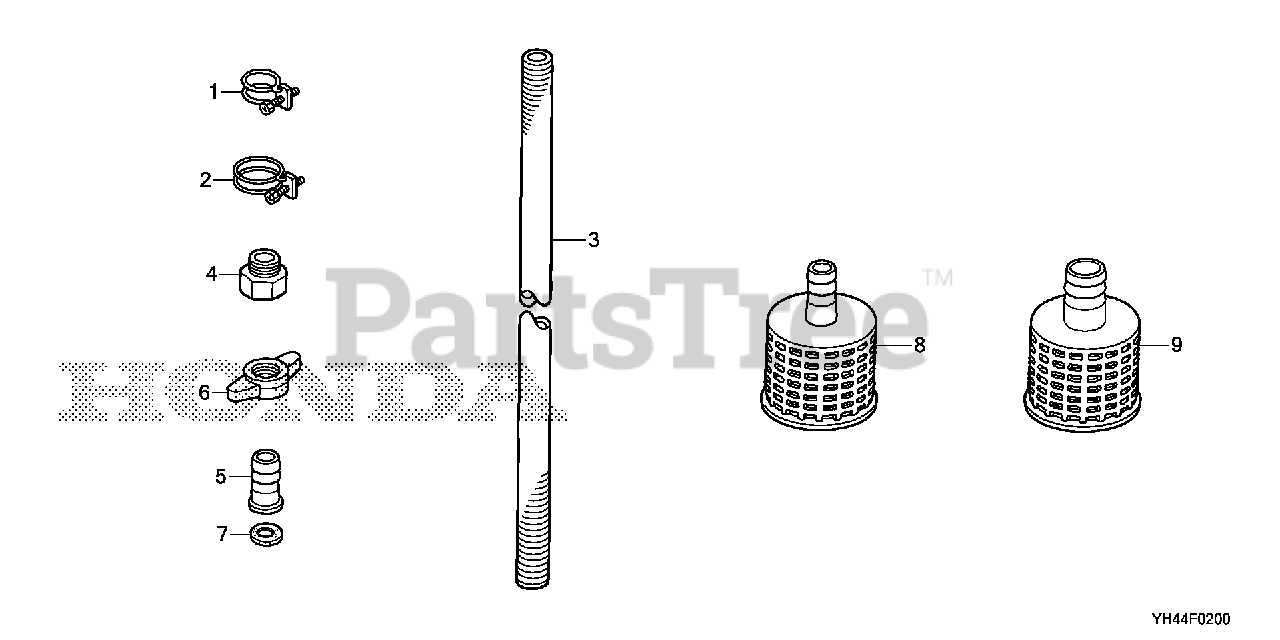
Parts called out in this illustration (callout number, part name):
1	BAND, HOSE
3	HOSE, SUCTION (5M)
5	COUPLING, HOSE
6	RING, HOSE CLAMP (NPT1)
7	GASKET, COUPLING
